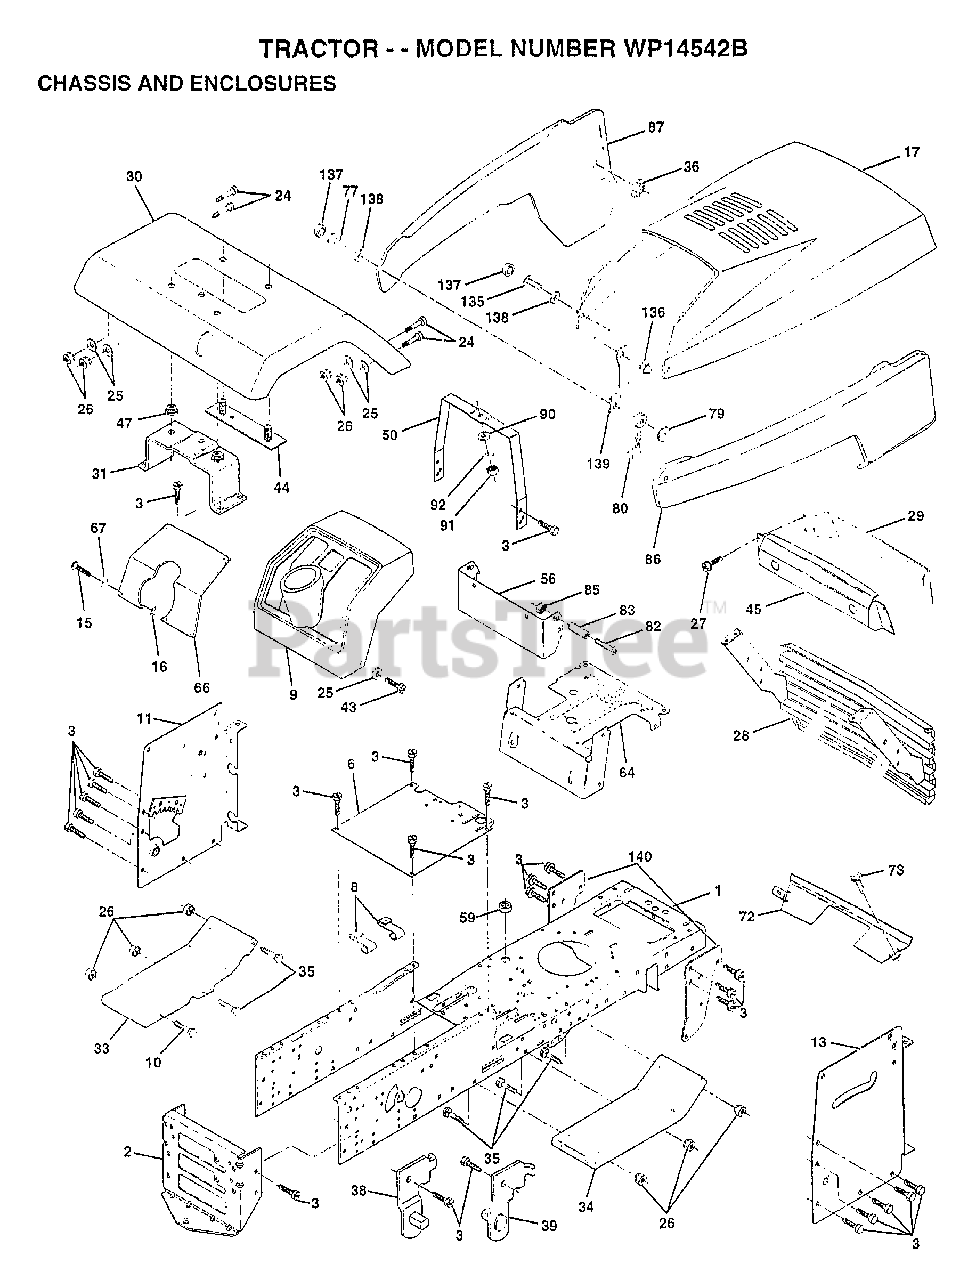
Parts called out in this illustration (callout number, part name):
1	CHASSIS ASM
3	SCREW
6	SADDLE
8	"CLIP,INSULATOR"
9	DASHBOARD BLACK
11	PANEL.DASH.LH.
13	PANEL.DASH.RH.
15	SCREW
24	BOLT
25	WASHER
26	NUT
28	GRILLE ASM PNT
29	LENS.BAR.CLEAR
31	BRKT.ASM.FENDER
33	FOOTREST.LH.LT/GT
34	FOOTREST.RH.LT/GT
35	BOLT
36	PAL NUT LT
38	BRACKET ASM LH
39	BRACKET ASM RH
43	SCREW GTV
44	STRAP ASM FENDER
45	BEZEL.ASM.
47	NUT-PUSH YT
50	DASH.SUPT.YP/HUSQ
56	EXT DASH LTYT
64	DASH.LOWER.LT
66	"PLATE-DASH,SLSCR"
67	WASHER
72	STRAP.GRILLE.PNT.
73	SCREW CRT
77	SCREW
79	WELDNUT
80	HOOD LATCH T
82	SCREW
83	SPACER LT
87	"PANEL SIDE,LH"
90	WASHER PM
92	LOCKWASHER
135	SCREW.10-24X3/8.
136	ACORN NUT RB
137	SNAP CAP LT
138	WASHER LT
139	BKT.SPT.HOOD/PANL
140	BRKT SUSPENSION
